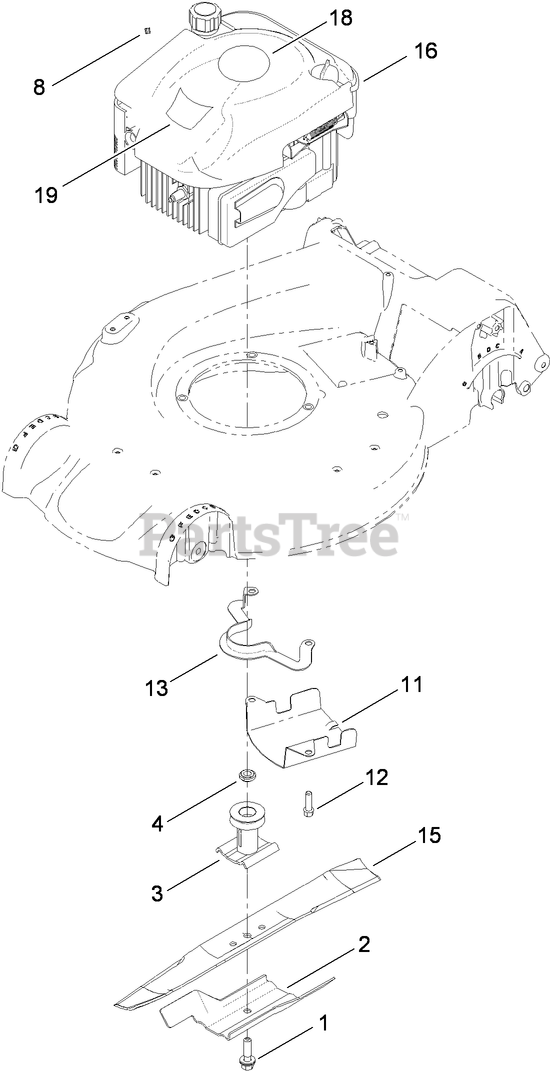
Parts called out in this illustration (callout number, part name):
2	ACCELERATOR-BLADE
3	DRIVER-BLADE
4	SPACER-DRIVER
8	STOP-ROPE
11	SHIELD-GRASS
12	SCREW-TAPTITE
13	GUIDE-BELT
18	DECAL-ENGINE
19	DECAL-RECOIL
